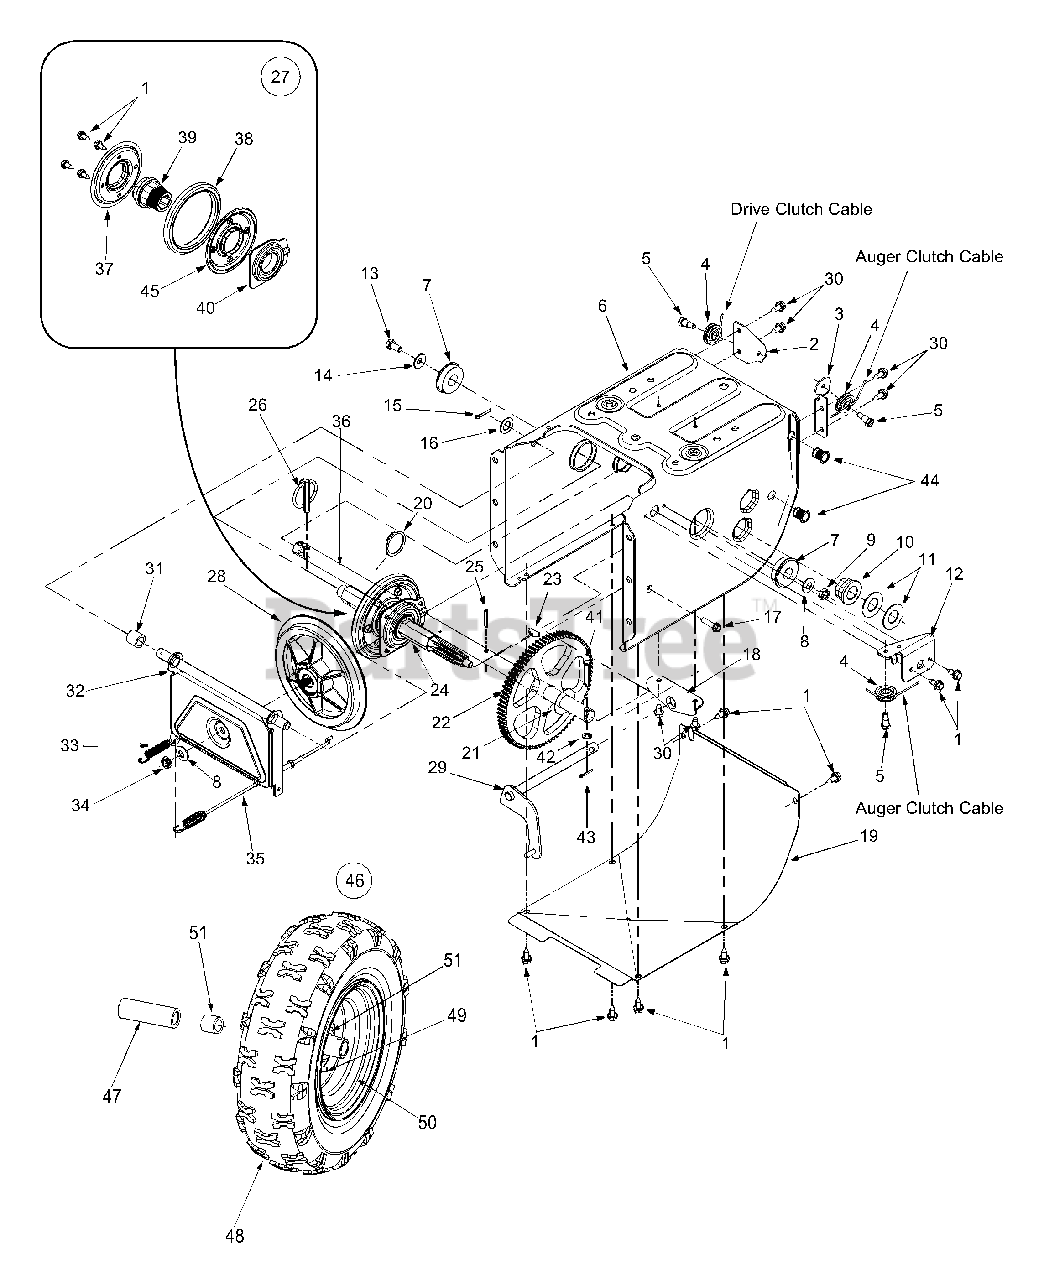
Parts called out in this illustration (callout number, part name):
1	Self-tapping Screw, 1/4-20 x.625
5	Hex Screw 1/4-28
6	Frame Assembly
7	Ball Bearing
8	Bell Washer
9	Lock Jam Nut
10	Hex Flange Bearing
11	Flat Washer
14	Bell Washer.340 ID x.872 OD
15	Cotter Pin
16	Flat Washer.536 ID x.930 OD
17	Self-tapping Screw, 1/4-20 x 1.25
21	Flat Washer.760 ID x.50 OD
22	80 Tooth Gear
24	7-Tooth Shaft
25	Roll Pin
26	Klik Pin
27	Friction Wheel Assembly
28	Friction Disc Wheel
29	Wheel Shift Rod Assembly
30	Self-tapping Screw, 1/4-20 x.5
31	Spacer
34	Jam Nut 3/8-24
35	Drive Cable
36	Axle 16" Wheels
37	Friction Plate
38	Friction Wheel Rubber
39	Friction Wheel Hub
40	Friction Wheel Bearing Assembly
41	Clevis Pin, 1/4 x 1.3725
42	Flat Washer,.281 x.5 x.063
43	Cotter Pin,.75
44	Insert Nut, 5/16-18
45	Friction Plate
47	Spacer
48	Tire Only
49	Air Valve
